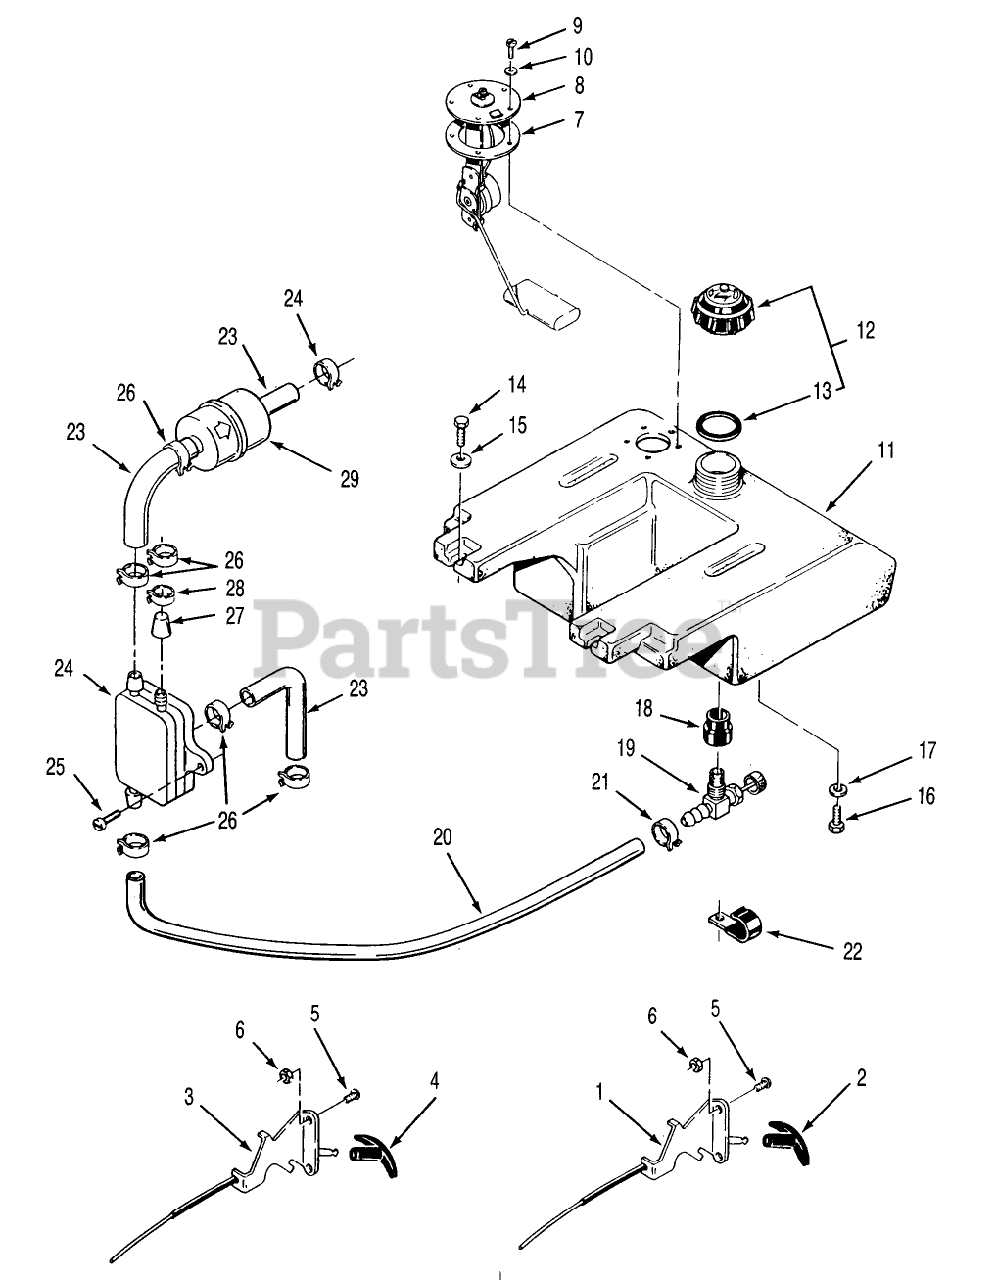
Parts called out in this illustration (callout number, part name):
2	KNOB-THROTTLE
3	CONTROL-CHOKE
4	KNOB-CHOKE
5	SCREW-PPH
7	GASKET-SENDER, FUEL
12	ASS'Y-GAS CAP
19	VALVE-FUEL
